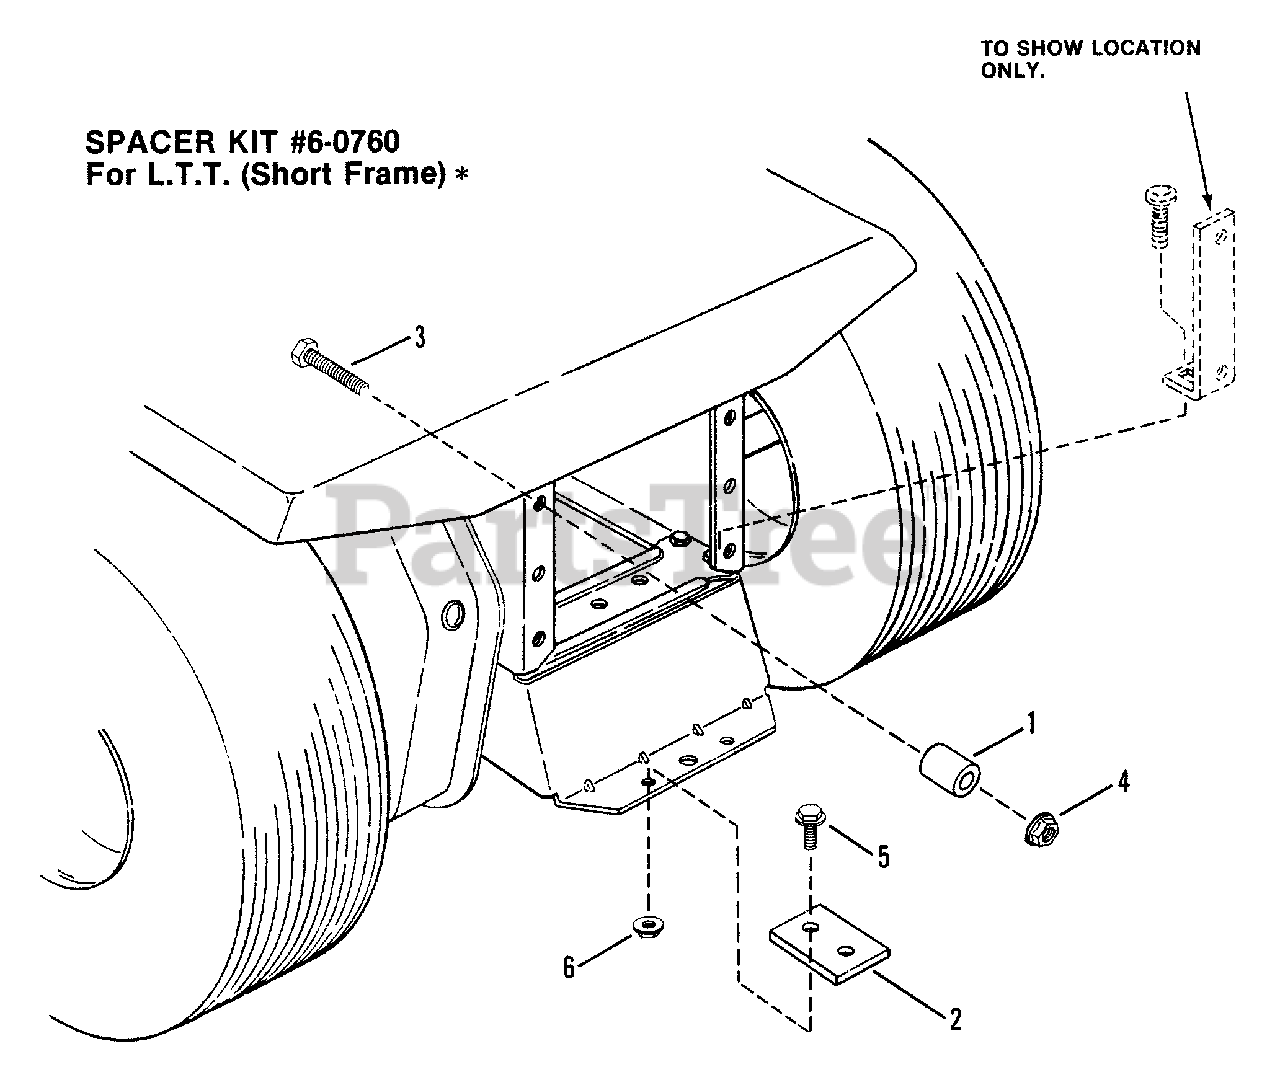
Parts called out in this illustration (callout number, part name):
2	SPACER, Drawbar
3	BOLT, 5/16-18x2"
4	NUT, 5/16-18 Hex Flange Lock
5	SCREW, 3/8-16x3/4" Hex Head Self-Tapping
6	NUT, 3/8-16 Hex Flange Lock
